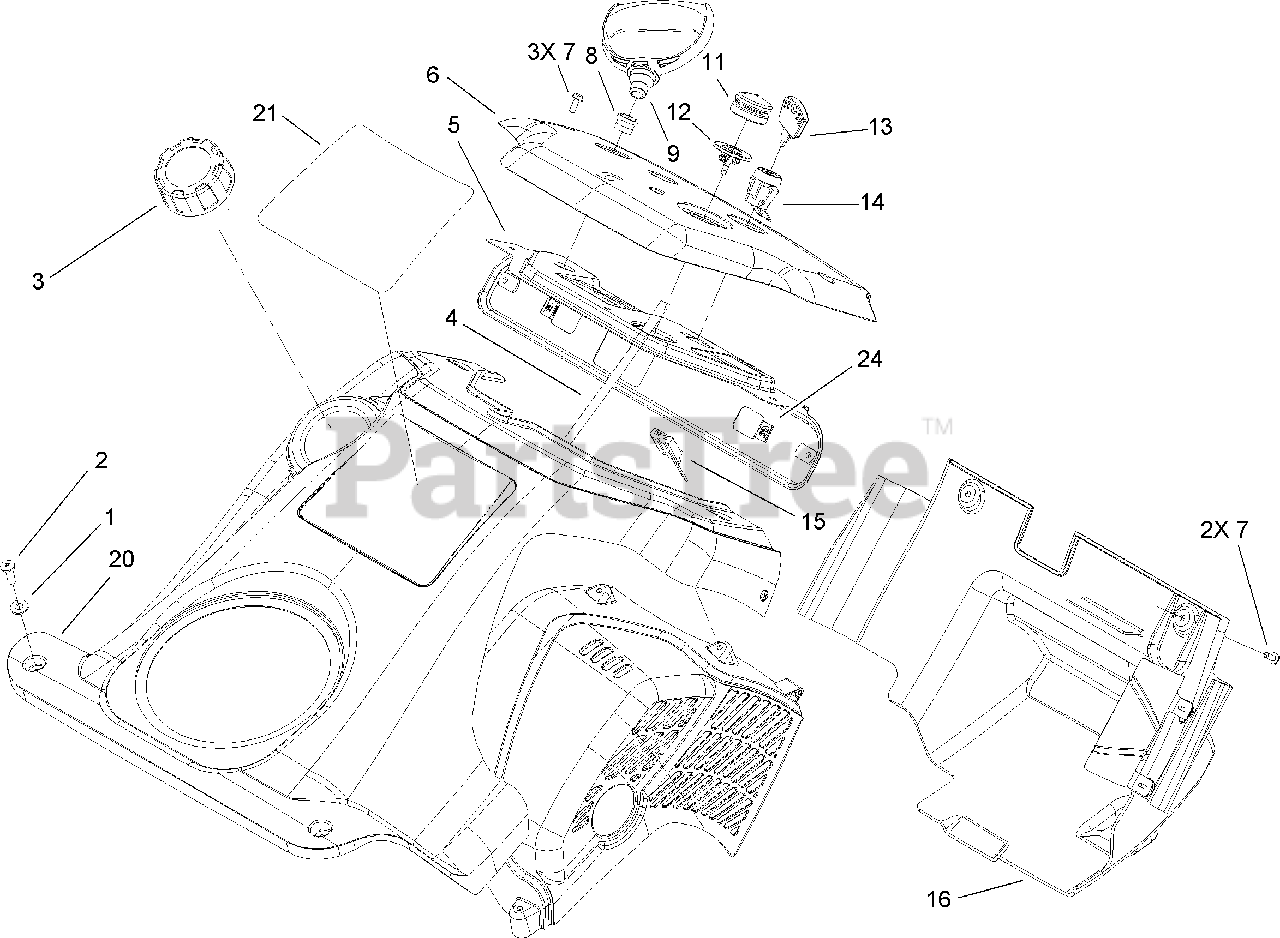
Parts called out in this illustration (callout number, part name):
1	WASHER-FLAT
2	SCREW-PPH
3	GAS CAP ASM
4	HOSE-PRIMER
5	PANEL-SUPPORT, CONTROL
6	PANEL-CONTROL
7	SCREW-HWH
8	GUIDE-ROPE, STARTER
9	HANDLE-RECOIL
11	BULB-PRIMER
12	BODY-PRIMER
15	CONNECTOR-BODY
16	LOWER SHROUD/BAFFLE ASM
20	UPPER SHROUD ASM
24	NUT-SPEED, U-TYPE
